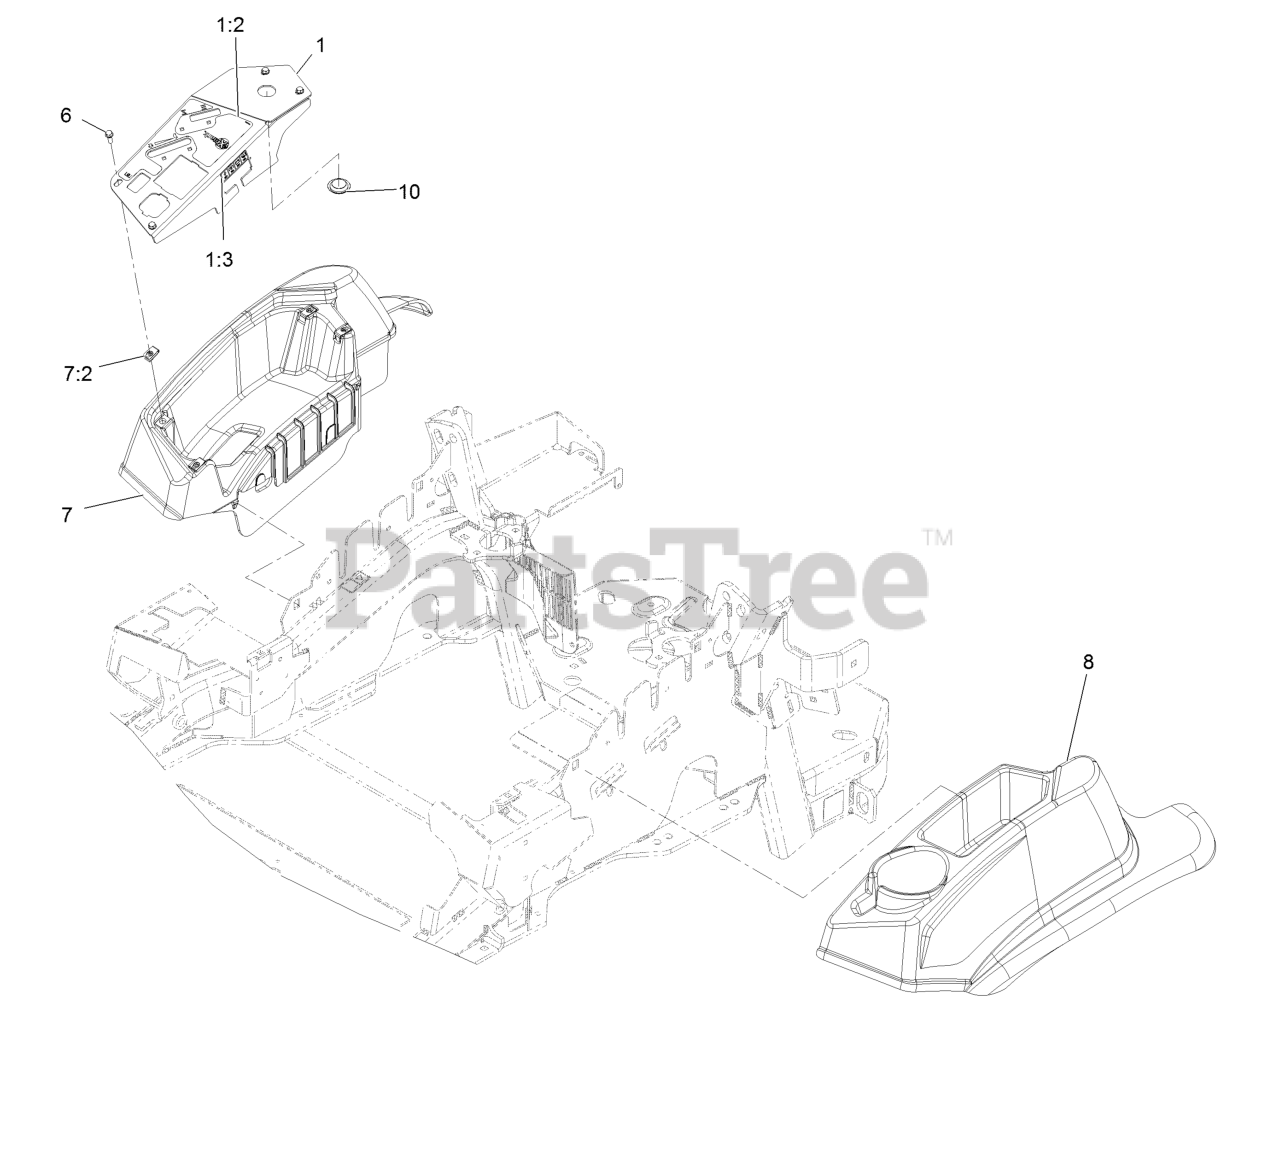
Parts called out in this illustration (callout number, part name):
1	ASM,Console Panel W/Decal
1:2	Decal-Control Panel Non-Efi
1:3	Decal-Fuses
6	Screw-Machine 1/4-20 X 3/4
7	Console,RH As ASM
7:2	Nut-Retainer-Panel 1/4-20
8	Console, LH As
10	Plug-Plastic
